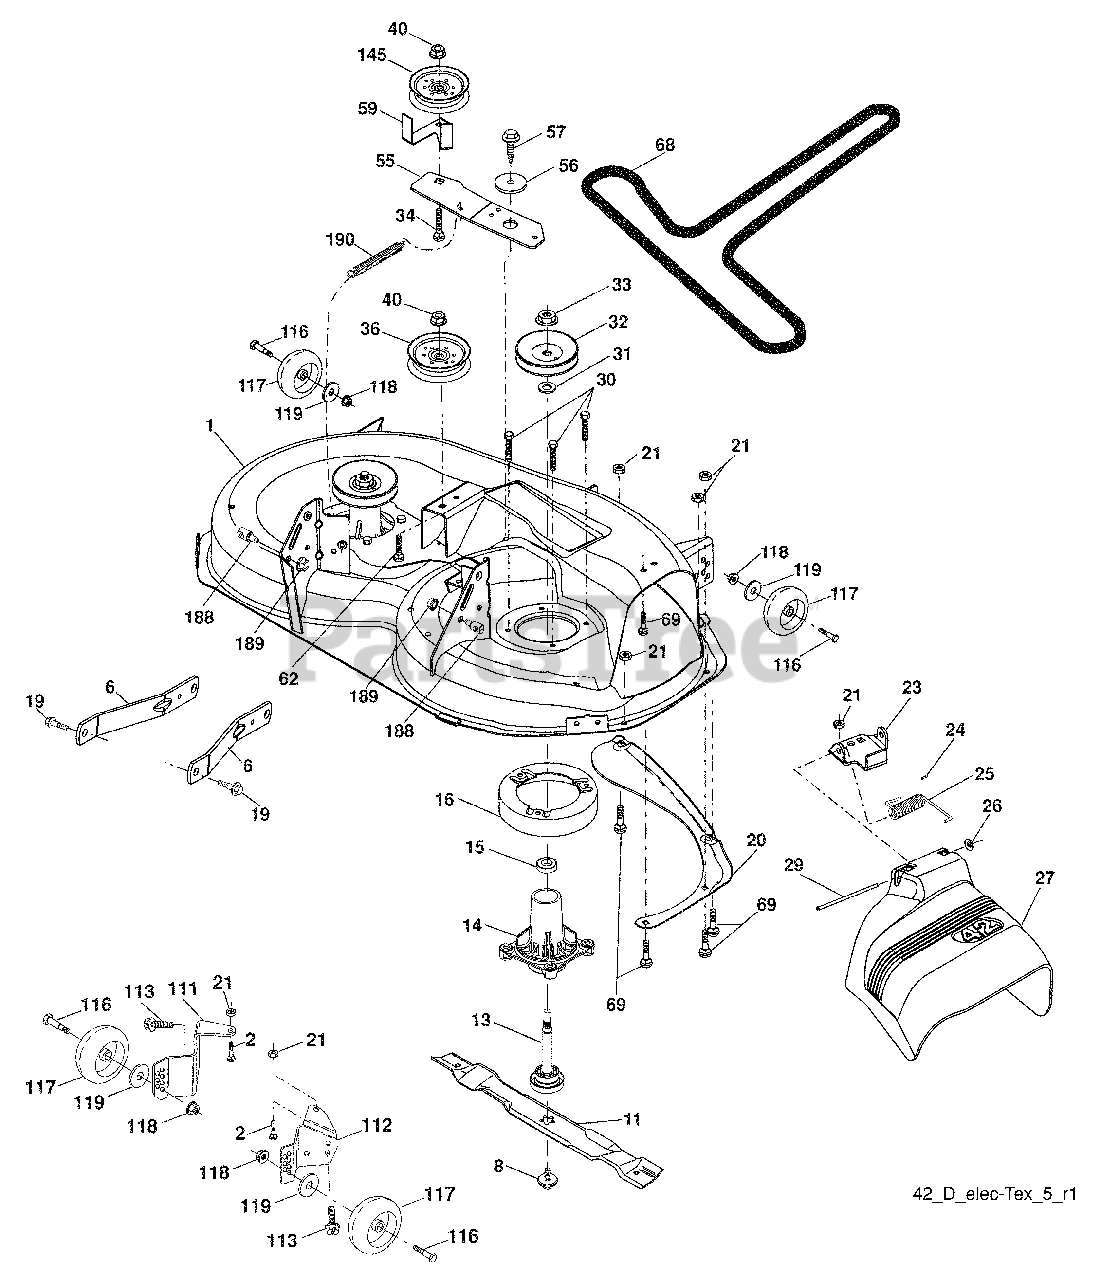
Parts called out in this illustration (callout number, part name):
1	Mower Housing
2	Bolt, Rdhd.5QNK 5/16-18 unc x 3/4
6	Arm Suspension
8	Bolt/Washer asm 7/16-20 unf
11	Blade Mower
13	Shaft Assembly, Mandrel
14	Housing, Mandrel
15	Bearing, Ball, Mandrel
16	Strippr Mandrel
19	Bolt, Shoulder
20	Baffle Vortex
21	Nut
23	Bracket, Deflector
24	Cap, Sleeve
25	Spring, Torsion, Deflector
27	Shield, Deflector
29	Rod, Hinge
30	Screw Thdrol Rolling Wsh Hd
31	Washer, Spacer
32	Pulley, Mandrel
33	Nut, Toplock, Flanged
34	Bolt Carr Sh. 3/8-16 x1-1/2 Gr. 5
36	Pulley, Idler, Flat
40	Nut, Lock Flg. 3/8-16 unc
55	Arm, Idler
56	Spacer, Retainer
57	Screw Hexwsh Thd 3/8-16 x 1
59	Guard, Tuv Idler (94)
62	Bolt 3/8 - 16 unc x 2
69	Bolt
111	Bracket Wheel Gauge LH
112	Bracket Wheel Gauge RH
113	Screw 5/16-18
116	Bolt, Shoulder
117	Wheel, Gauge
118	Nut Centerlock 3/8 - 16 unc
119	Washer 3/8 x 7/8 x 14 Ga.
145	Pulley Idler
188	Stud Fastener
189	Nut Lock Hex Flange
190	Spring Mower Drive
